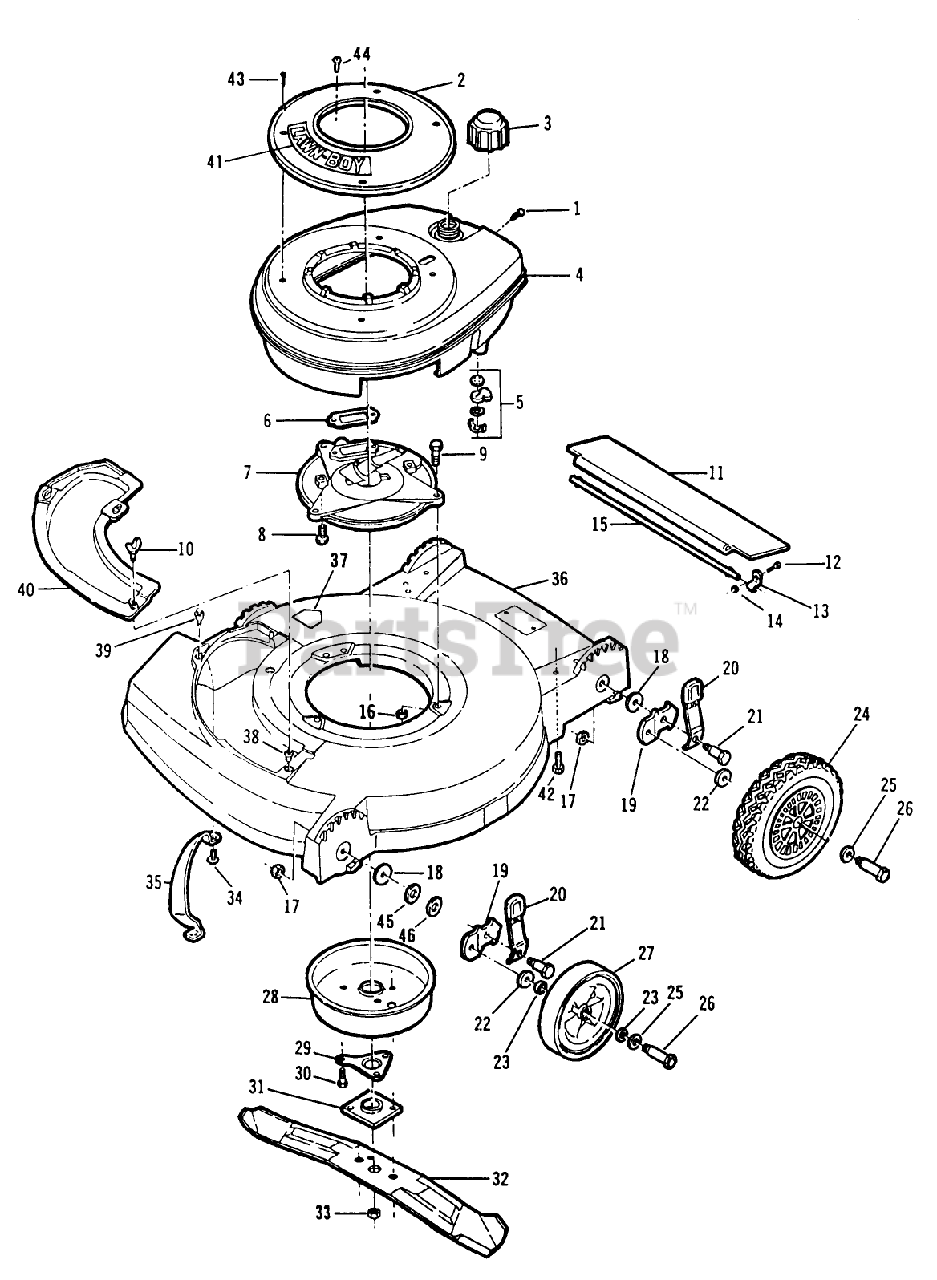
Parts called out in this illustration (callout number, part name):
1	SCREW S
3	FUEL CAP & INSERT
5	SHUT OFF VALVE KIT
7	PLATE F
8	SCREW V
9	SCREW-HH
10	WING SCREW LAWRE
13	CLAMP ROD KMC
14	LOCKNUT E
15	ROD T/SHIELD ADV WIRE
16	NUT-LOCK F
17	LOCKNUT
18	WASHER
20	SPRING ARM ASM
21	BOLT
22	WASHER WROUGHT
23	Felt Washer
24	WHEEL&TIRE 8" TRI
25	SPACER
26	BOLT WHEEL
28	MUFFLER COVER F
29	SUPPORT F
30	SCREW
31	PLATE AND COLLAR ASM
33	NUT-BLADE
35	TOE BAR 19"
42	SCREW
43	SCREW - SELF TAPPING
44	SCREW SEMS SM
45	WASHER
46	WASHER
